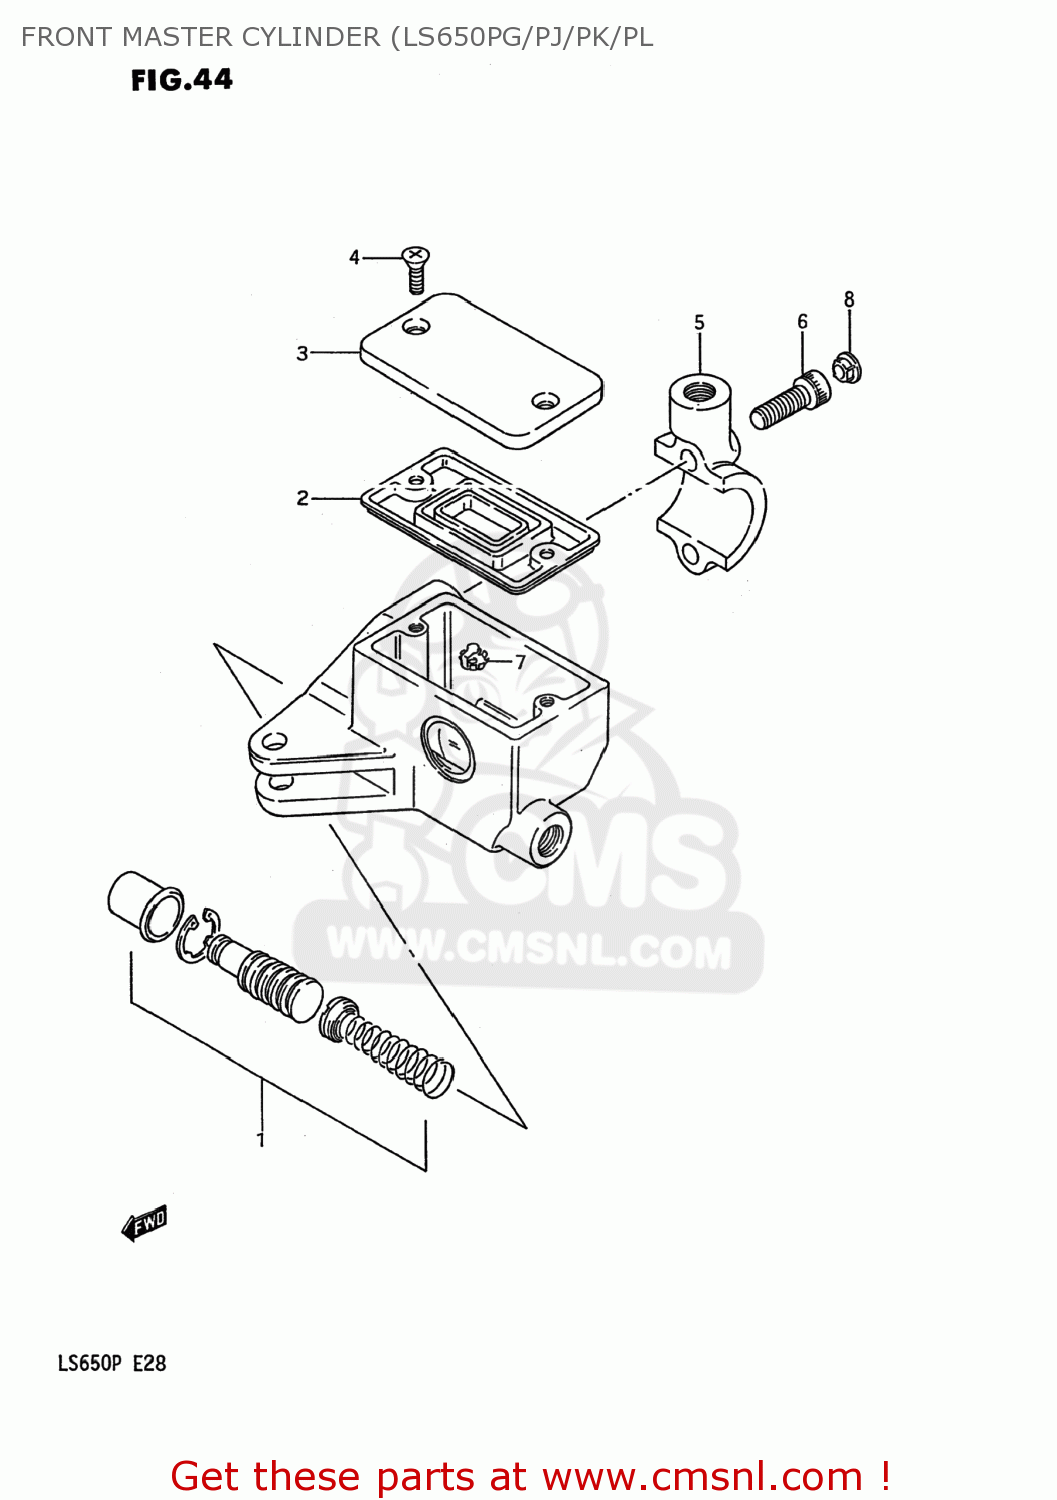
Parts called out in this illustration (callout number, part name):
1	CUP SET,MASTER CYLINDER
2	3-1
3	CAP
4	SCREW,RESERVOIR CAP
5	HOLDER
6	BOLT ,6X20
7	PROTECTOR
8	CAP(OD:10)
